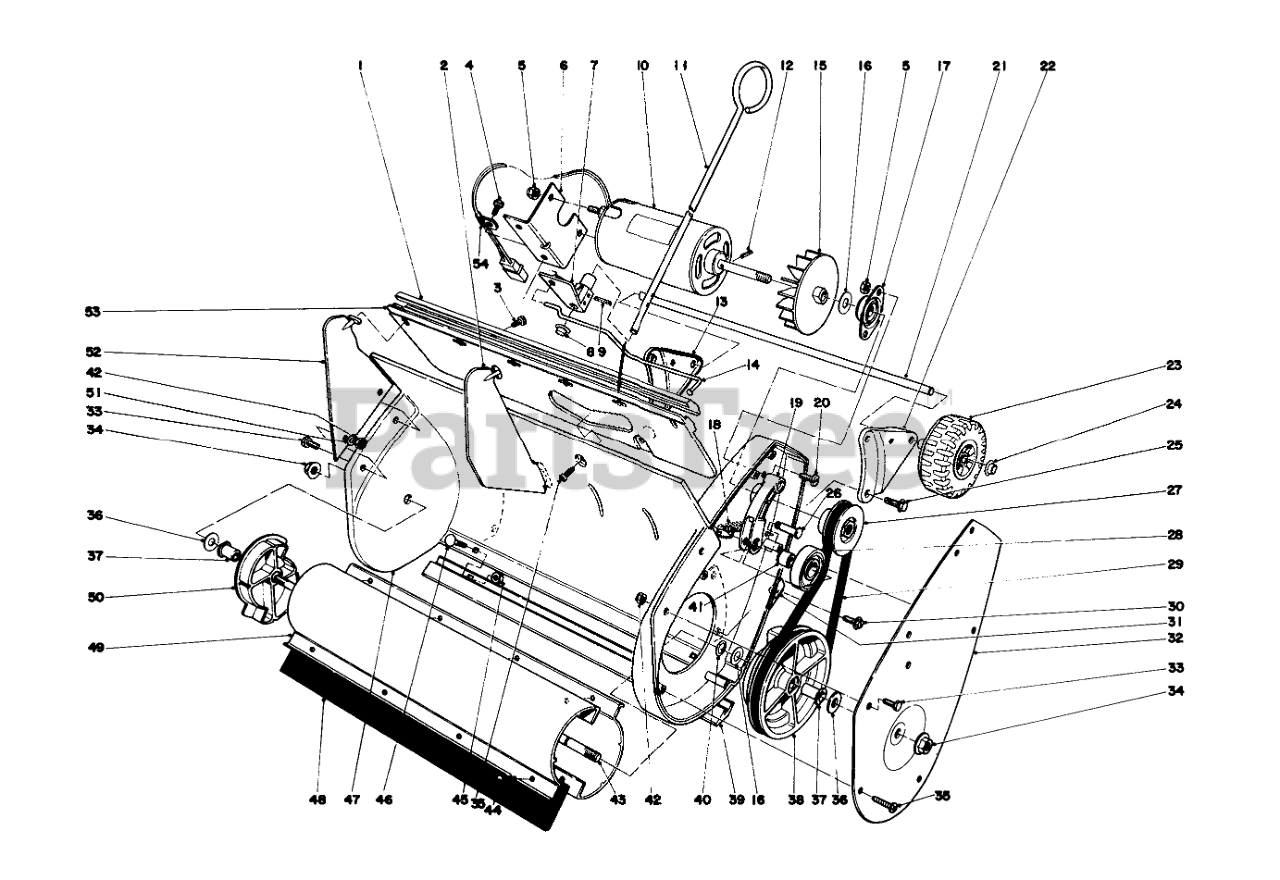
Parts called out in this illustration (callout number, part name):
1	MOULDING
2	VANE INNER
3	10-16 X 3/8 THDG SCREW
5	NUT-LOCK, NI
6	MOUNTING BRKT B
7	VANE ADJ BRKT
8	NUT-SPEED
10	Motor
11	VANE ADJ ROD
12	PIN-ROLL
13	Wheel Bracket R.H.
14	Linkage Vane Adjustment
16	WASHER-THRUST
17	SIDE FLANGE BRG
18	Idler Spring
19	Idler Arm
20	Screw
21	Axle Shaft
22	Wheel Bracket L.H.
23	S-120 WHEEL
24	PUSHNUT-CAP, WASHER
25	SCREW-HWH
26	Pin Idler
27	DRIVE PULLEY
28	BEARING-BALL
30	SCREW-HWHTF
31	NUT-TYPE J
32	Cover-Belt Case
33	SCREW-HWH
34	NUT-HF
35	Screw
36	Thrust Washer
37	BUSHING ROTOR
38	Pulley-Driven
39	Scraper
40	Retaining Ring
41	SPACER
42	NUT-LOCK, NI
43	ROTOR SHAFT
44	Screw
45	NUT-KEPS
46	SCREW-CARR
47	Housing
48	Blade-Rotor
49	ROTOR
50	END CAP ROTOR
51	Washer
52	VANE OUTSIDE
53	Vane Mount
